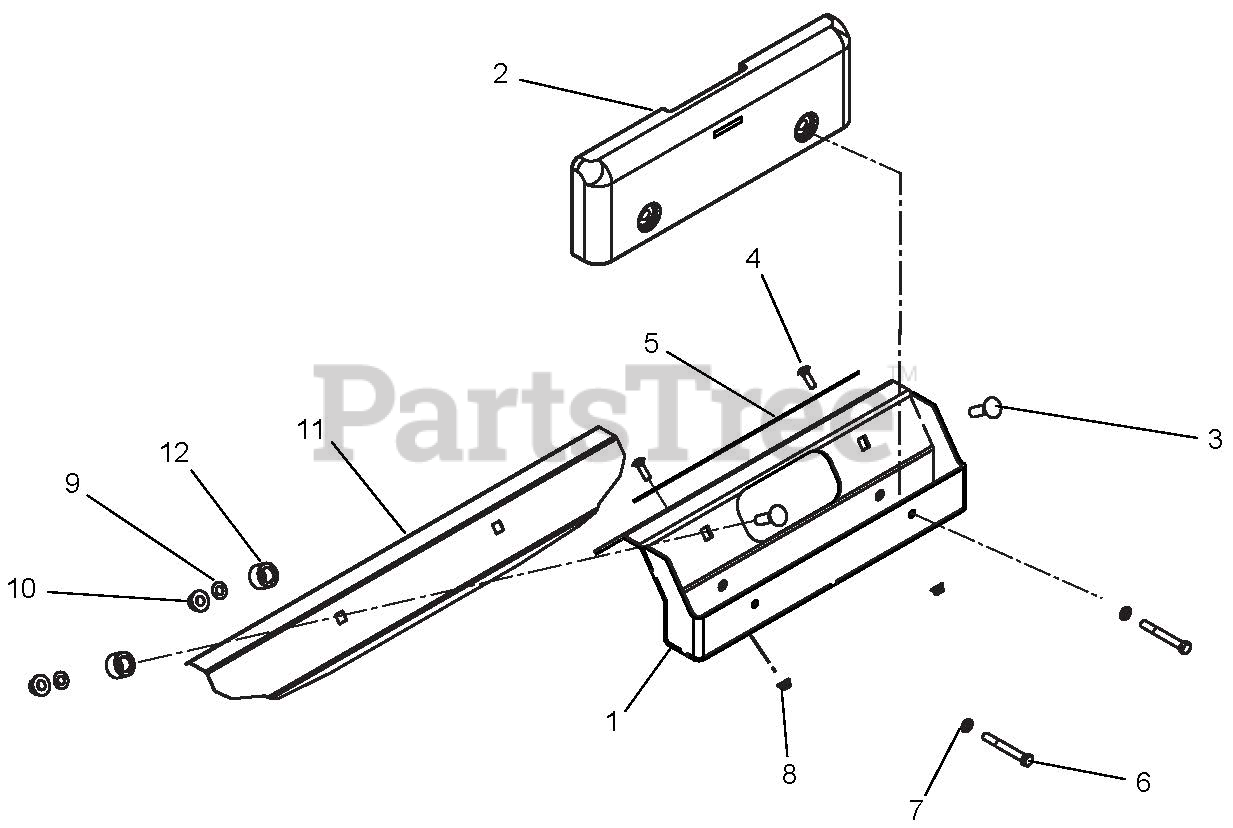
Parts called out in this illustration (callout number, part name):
1	Weldment, Bagger Weight Tray
2	Cast Iron Weight
3	Bolt, Round Head Square Neck 1/2-13 x 2.00
4	Bolt, Round Head Square Neck 1/2-13 x 1.00
5	Grip, Adhesive
6	Bolt, Hex 3/8-16 x 3.00
7	Washer, Lock 3/8
8	Nut, Nyloc 5/16-18
9	Nut, Push
10	Nut, Flange Nyloc 1/2-13
11	Footrest
